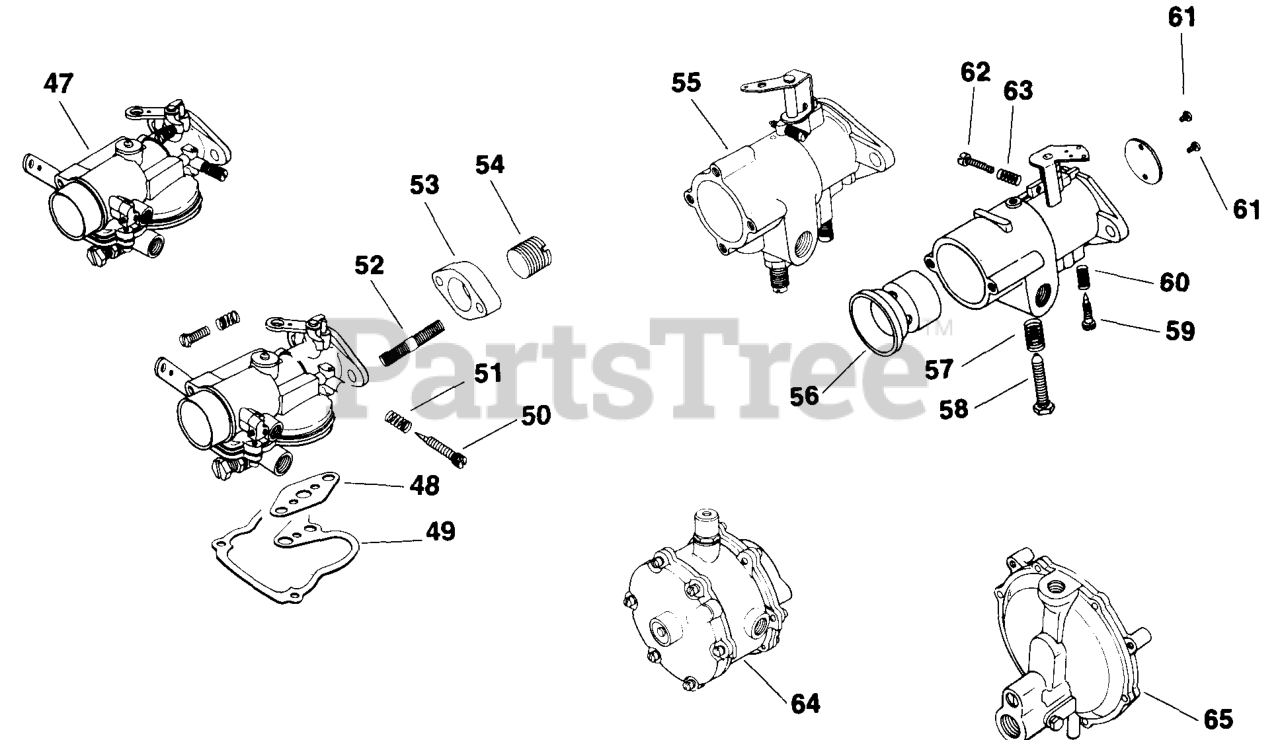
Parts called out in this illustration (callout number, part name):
55	CARBURETOR - DISCONTINUED
59	SCREW - DISCONTINUED
60	SPRING - DISCONTINUED
61	SCREW - DISCONTINUED
62	SCREW - DISCONTINUED
63	SPRING - DISCONTINUED
